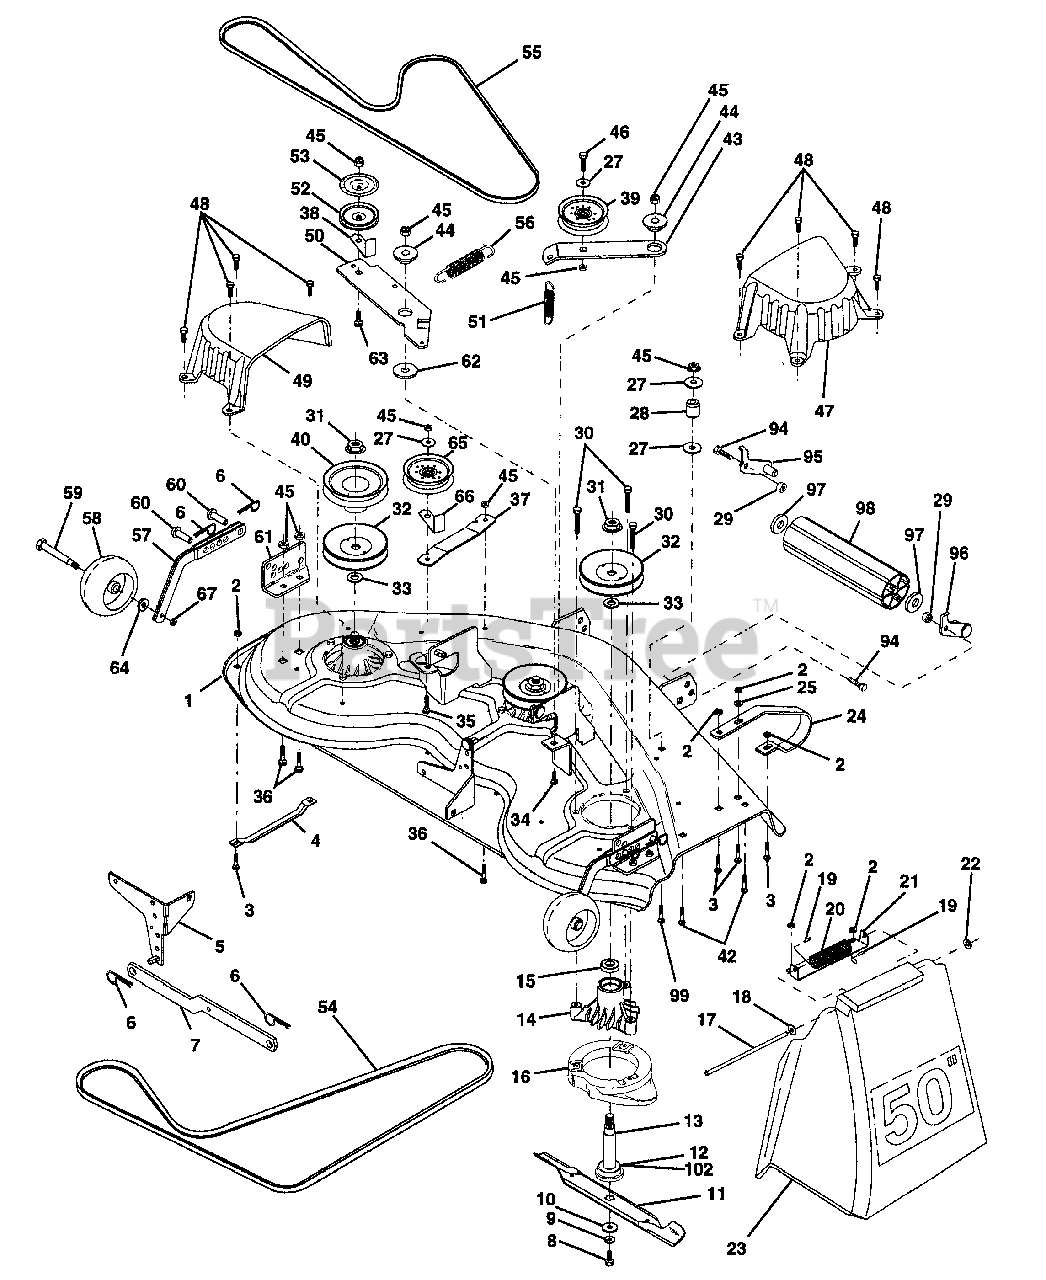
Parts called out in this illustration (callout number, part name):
1	Deck Asm., Mower 50" Vented
2	Nut, Crownlock 5616-18 Unc
3	Bolt, Carriage 5/16-18 x 3/4
4	Runner, Mower LH
5	Bracket Asm., Sway Bar
6	Retainer, Spring
7	Arm Suspension, Rear
8	Bolt 3/8-24 x 1.25 Gr. 8 Patched
9	Washer, Lock Hvy 3/8 Unplated
10	Washer, Hard Blade Mower Vented
11	Blade (3 Required)
12	Bearing, Ball #6204 (Mandrel)
13	Shaft Asm., W/Lower Brg
14	Housing, Mandrel 50" Vent
15	Bearing, Ball Mandrel
16	Stripper, Mower Vented
17	Rod, Hinge
18	Washer 11/32 x 5/8 x 16 Ga.
19	Cap, Sleeve
20	Spring, Torsion Deflector
21	Bracket, Deflector
23	Shield, Deflector Mower
24	Runner, RH
25	Washer 11/32 x 3/4 x 16 Ga.
27	Washer 13/32 x 13/16 x 16 Ga.
28	Spacer, Spring Stop Idler
29	Nut, Lock Hex W/Wsh 3/8-16 Unc
30	Screw Thdrol Hex Head
31	Nut, Flg Top Lock Cntr 9/16
32	Pulley, Mandrel
33	Washer, Spacer Mower Vented
34	Bolt, Carriage 3/8-16 x 1-1/4
35	Bolt, Carriage 3/8-16 x 2
36	Bolt, Carriage 3/8-16 x 1 Gr. 5
37	Stiffener, Arm Idler
38	Keeper, Belt Idler
39	Pulley, Idler Flat
40	Pulley, Driven
42	Bolt, Carriage 5/16-18 Unc x 3/4
43	Arm, Idler Secondary
44	Spacer, Retainer
45	Nut, Crownlock 3/8-16 Unc
46	Bolt, Fin Hex 3/8-16 Unc x 1-3/4
47	Cover, Mandrel RH
48	Screw, Thd Roll 1 /4-20 x 5/8
49	Cover, Mandrel LH
50	Arm, Idler Primary
51	Spring, Secondary
52	Pulley, Idler V Groove
53	Shield, Idler
54	V-Belt, Mower Primary
55	V-Belt, Mower Secondary
56	Spring, Primary
57	Bar Asm., Wheel Gauge
58	Wheel, Gauge
59	Bolt, Shoulder
60	Pin, Clevis
61	Bracket, Wheel Gauge
62	Washer Hardened
63	Bolt Carriage 3/8-16 x 1-1/2
64	Washer 3/8 x 7/8 x 14 Ga.
65	Pulley Idler Flat Mower
66	Keeper, Belt Idler 44/50
67	Nut, Center Lock 3/8-16
94	Bolt, Fin Hex 3/8-16 UNC x 1
95	Bracket, Asm. Noseroller LH
96	Bracket, Asm. Noseroller RH
97	Washer 17/32 x 7/8 x 16 Ga.
98	Roller, Nose
99	Bolt, Carriage 3/8-16 x 1-3/4 Gr. 5
102	Washer Felt
